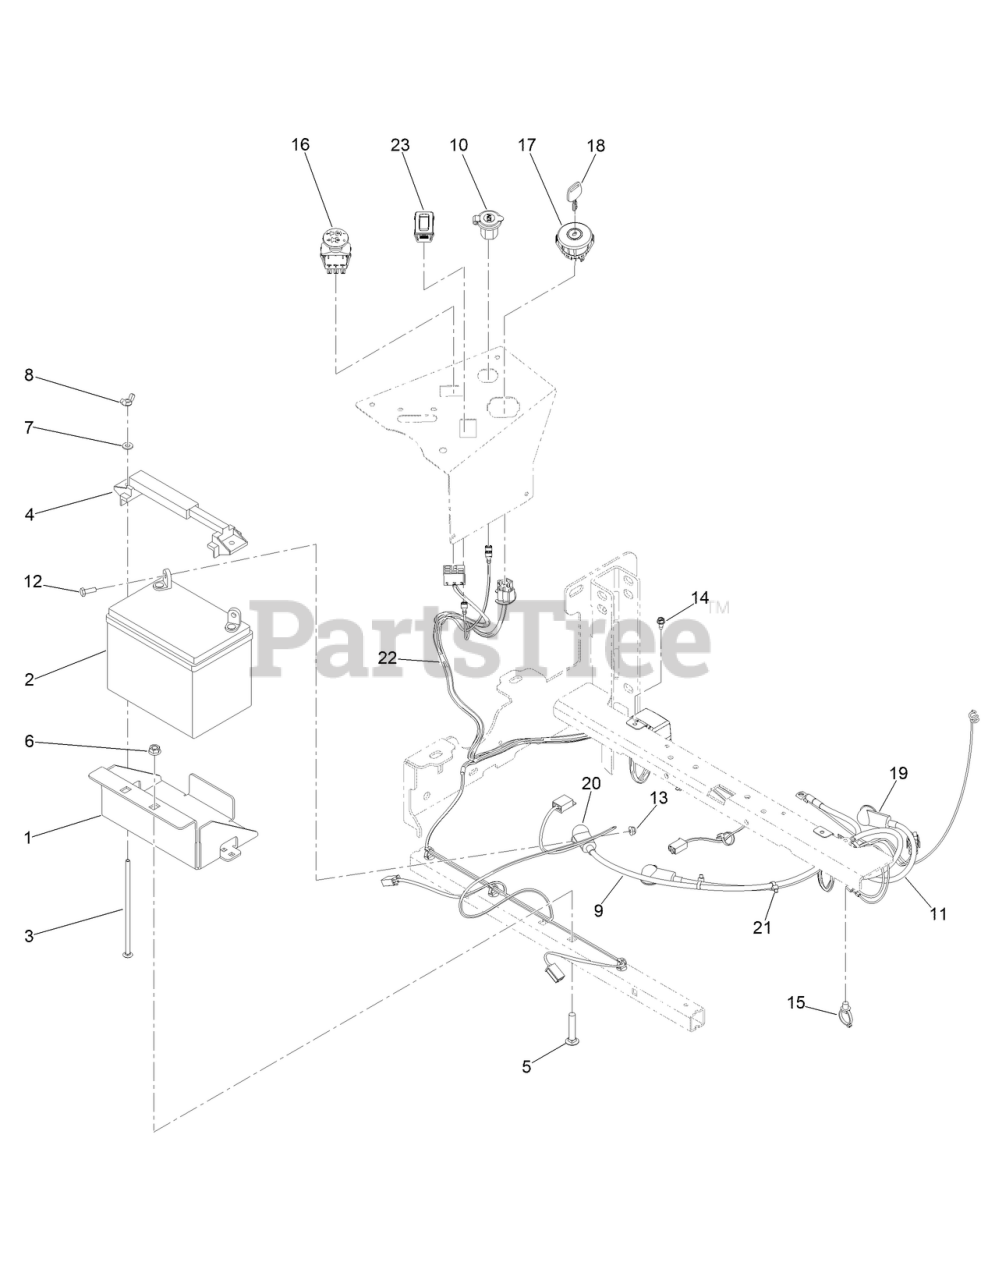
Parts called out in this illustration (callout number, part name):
1	MWR BATTERY BOX
2	12 VOLT START BATTERY 300CCA
3	1/4-20 X 7 CARRIAGE BOLT ZINC
4	BATTERY HOLD DOWN
5	SCREW-CARR
6	3/8-16 HEX FLANGE NUT W/SERR ZINC YELLOW
7	WASHER-FLAT
8	NUT-WING
9	MWR NEGATIVE CABLE 28
10	12 VOLT AUXILLIARY PLUG
11	MWR POSITIVE BATTERY CABLE 25IN
12	SCREW-HH
13	NUT-HF
14	SCREW-HWH
15	CLIP-TIE
16	PTO SWITCH
17	IGNITION SWITCH
18	2023 MWR KEY
19	3.15 LGTH STRAIGHT INSUL TERM COVER RED
20	STRAIGHT INSULATING TERMINAL COVER
21	TIE-CABLE
22	HARNESS-WIRE
23	HOUR METER
